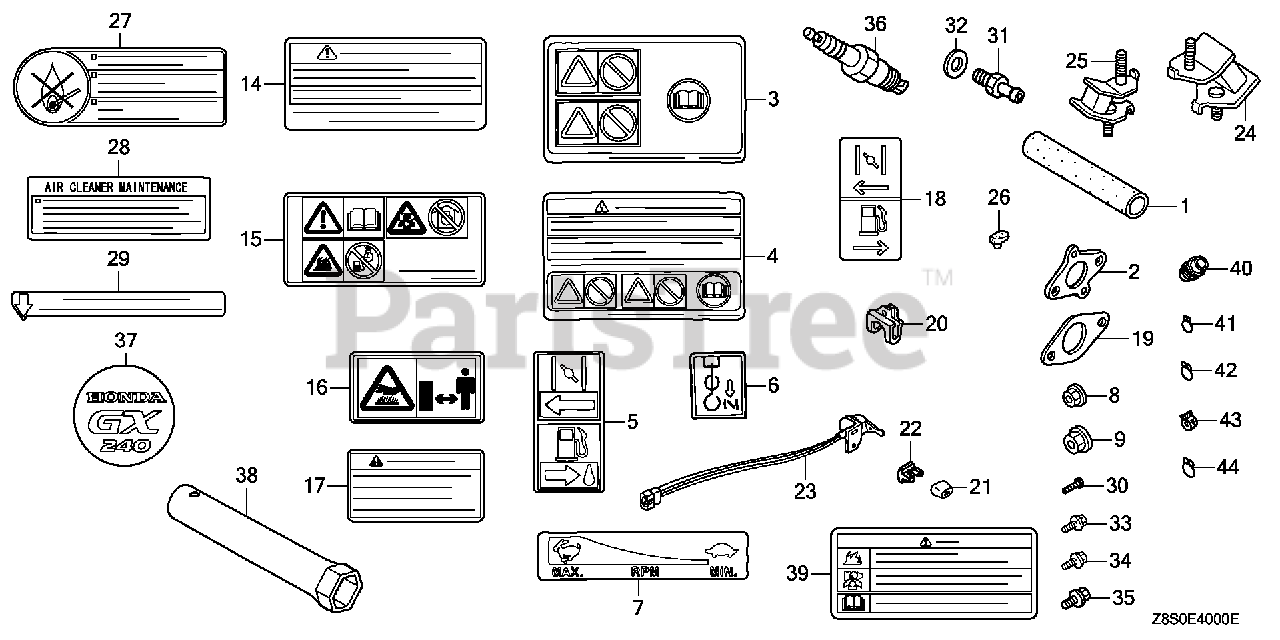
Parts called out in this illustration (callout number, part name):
14	MARK, OPERATOR CAUTION (FRENCH)(MADE IN THAI)
15	MARK, OPERATOR CAUTION (PICTOGRAPH)
16	MARK, EX. CAUTION (PICTOGRAPH)
17	MARK, EX. CAUTION (FRENCH)
